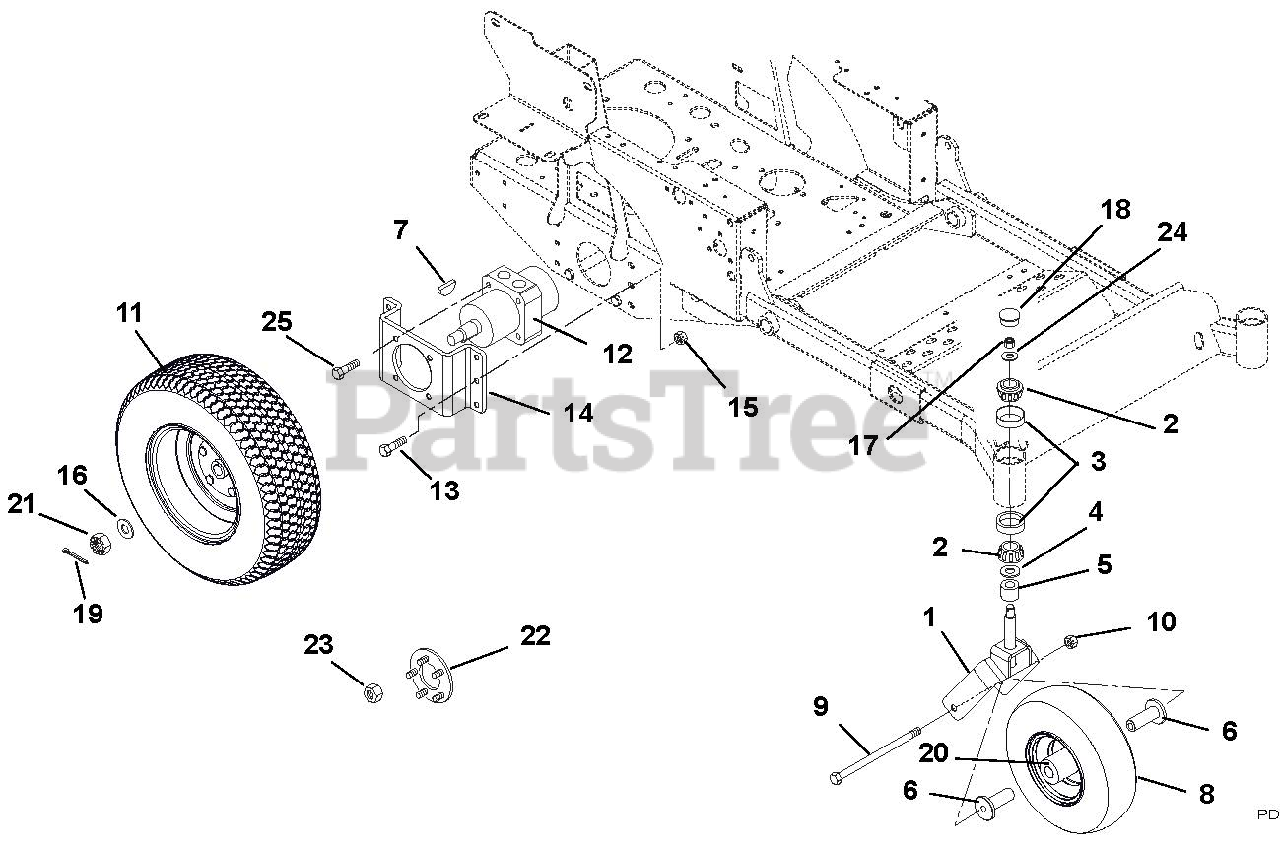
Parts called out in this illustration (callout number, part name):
1	Weldment, Front Fork
2	Bearing, Cone with Grease, 1.0 x .58
3	Bearing, Cup 1.980 x .420
4	Bearing Seal 1.5 x 2 x .18
5	Spacer, PM, 1.03 I.D. x 1.5 O.D. x .375
6	Spacer, Wheel
7	Key, Woodruff .31 x 1.00
8	Tire/Wheel Assembly, 13 x 5.00-6
8	Tire, 13 x 5.00-6
9	Bolt, Hex .50-13 x 7.50 Grade 5
10	Nut, Nyloc Flange .50-13
11	Tire/Wheel Assembly, 21 x 7.00-10
11	Tire, 21 x 7.00-10
12	Motor, Hydraulic Wheel
13	Bolt, Hex .38-16 x 1.00 Grade 5
14	Bracket, Wheel Motor
15	Nut, Nyloc Flange 3/8-16
16	Washer, Flat Steel .755 x 1.375 x .062
17	Nut, Center Lock Jam .75-16
18	Cap, Dust
19	Pin, Cotter .09 x 1.25 Extended Prong Square Cut
20	Bearing, 25mm I.D. x 52mm OD x 15mm
21	Nut, Hex .75-20
22	Assembly, Service Hub with Studs
23	Wheel Nut .437-20
24	Washer, Flat, Steel .812 x 1.250 x .062
25	Bolt, Hex .38-16 x 1.00 Grade 8 Epoxy 30
